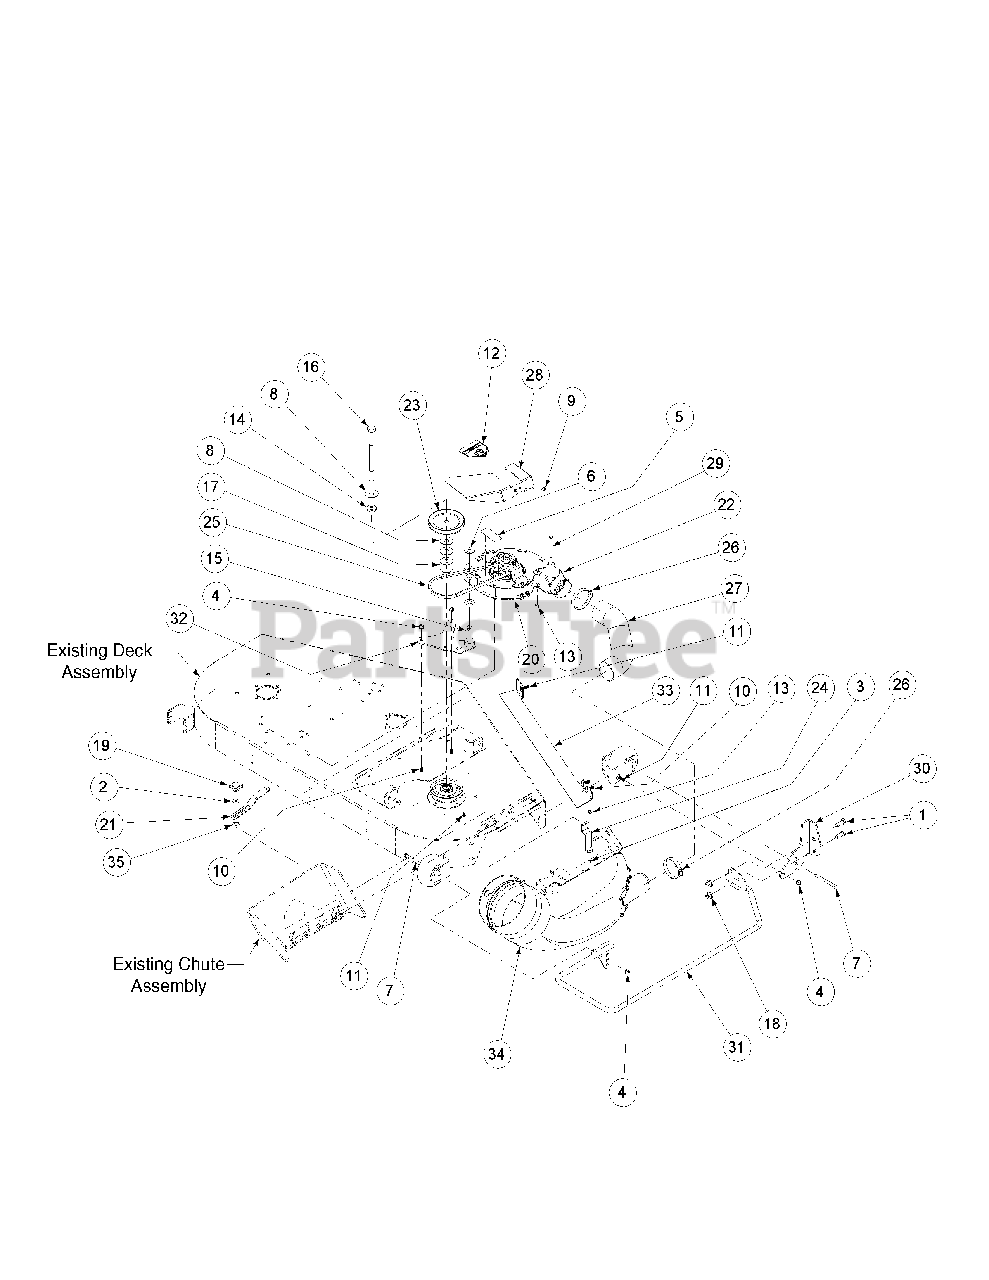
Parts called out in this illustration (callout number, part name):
1	HHCS, 1/2-13 x 1.25
2	Flat Washer, 3/8
3	Hex Cap Screw, 1/4-20, .75
4	Hex Nut Flange Lock, 3/8-16
5	Decal, Warning Shield Missing
6	Flat Washer, .76 x 1.49 x .06
7	HHCS, 3/8-16 x 4.50
8	Flat Washer, .781 ID x 2.00 OD x .105
9	Screw, TT, 1/4-20, 0.5, Hex Index Washer
10	Carriage Bolt, 3/8-16 x 1
11	Carriage Screw, 3/8-16 x 1.25
12	Decal, Danger Hands & Feet
13	Lock Nut, 1/4-20
14	Spacer, .812 ID x .268 Lg.
15	Cotter Pin, .148 x 3.00
16	Hex Cap Screw, 3/4-16, 9.00
17	Spacer, .76 OD x 2.00 OD x 1.39
18	Nut, 1/2-13, Flange Lock
19	Plastic Knob
20	Blower Assembly
21	Tension Assembly
22	Adaptor Tube
23	Pulley, V-Type 5.5 Dia.
24	Chute Stop Deflector Bracket
25	V-Belt
26	Hose Clamp, 3.00 Dia.
27	Hose Duct
28	Deck Blower Deflector Cover
29	HHCS, 1/4-20 x 3.50
30	MCS Guard Plate
31	MCS Guard Weldment
32	Pivot Weldment
33	Baffle Bracket
34	Chute Elbow Assembly
35	Push Retainer
